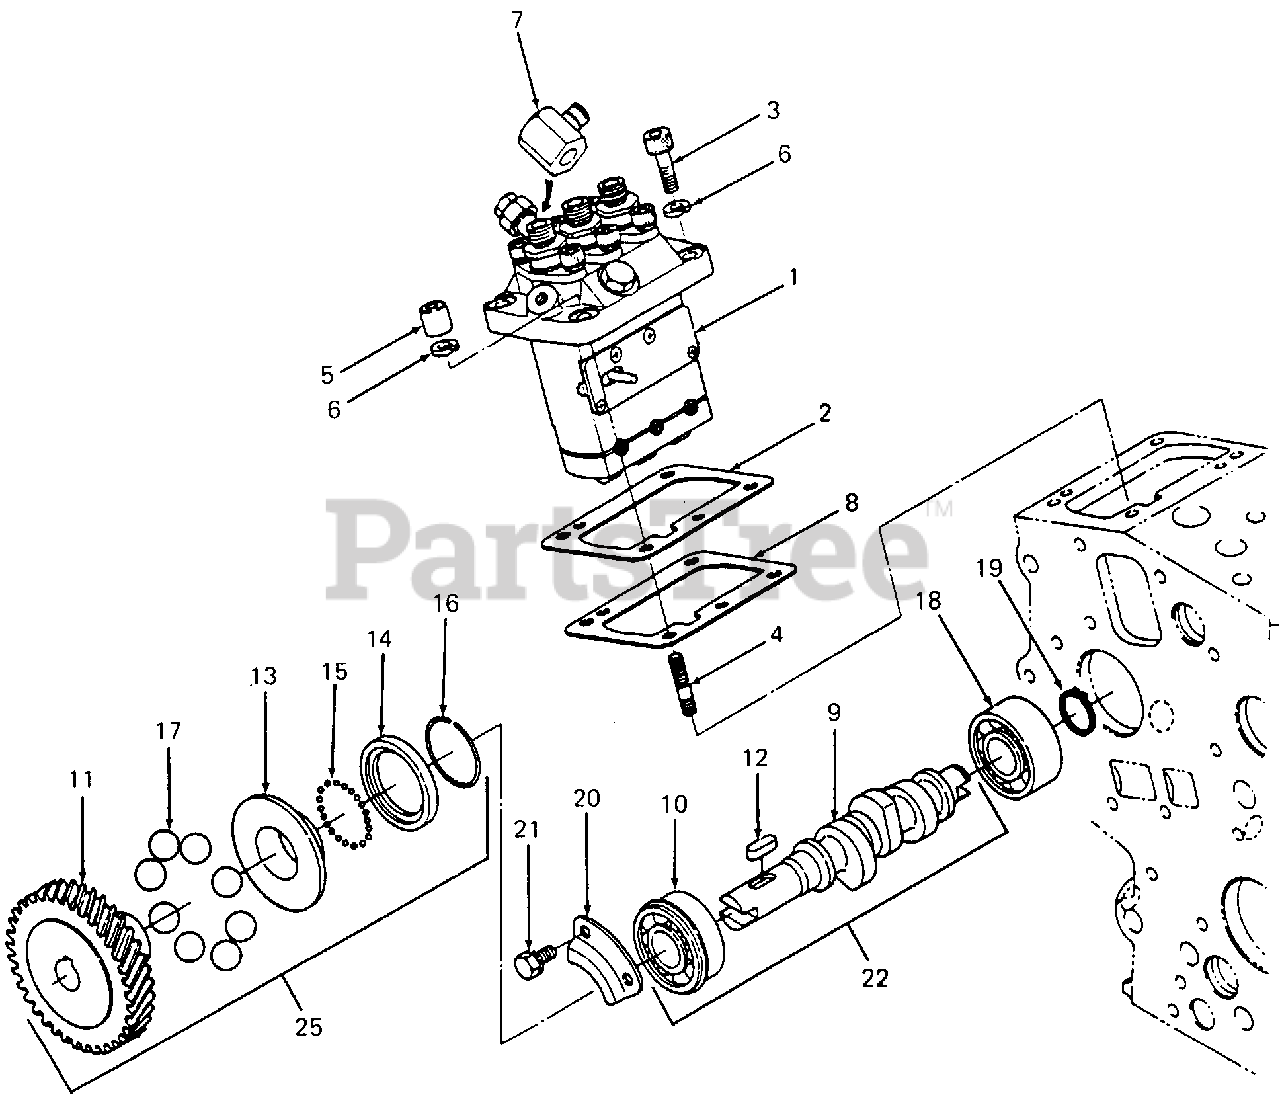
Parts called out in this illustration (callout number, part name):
1	Pump, Injection
2	Shim, Injection Pump
3	Screw, Socket Head
6	Washer, Lock
8	Shim, Injection Pump
9	Camshaft, Fuel Injection
10	Bearing, Ball
11	Gear, Injection Pump
13	Sleeve, Governor
14	Case, Governor Ball
15	Ball, Metal, 1/8 Dia
16	Ring, Governor Sleeve Retaining
17	Ball, Metal, 17/32 Dia
18	Bearing, Ball
19	Ring, External Retaining
20	Stop, Fuel Camshaft
21	Screw, Hex Cap w/Washer
22	Camshaft Assy, Fuel Injection
25	Camshaft Assy, Fuel Injection
